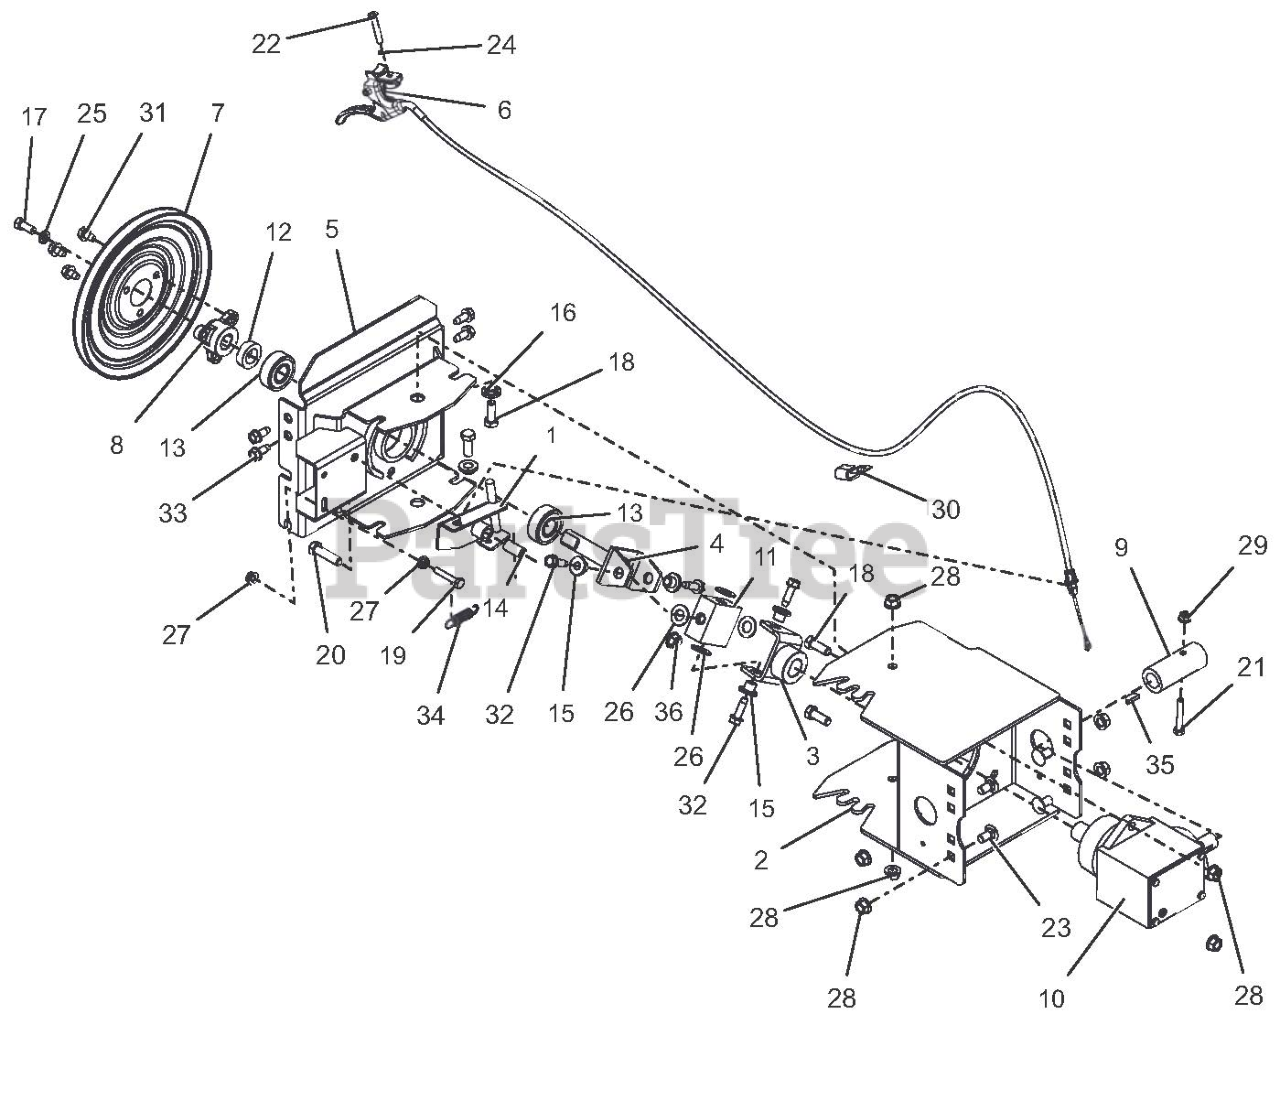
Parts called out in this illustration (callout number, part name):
1	ARM, PIVOT LOCK
2	ADAPTER, BROOM FRAME
3	JOINT,UNIVERSAL
4	JOINT,UNIVERSAL
5	ADAPTER, FRAME-20000 SERIES
6	CABLE, REMOTE BRUSH LOCK
7	PULLEY,SPIN FORM SINGLE GROOVE
8	PULLEY HUB, BOLT-ON D-BORE .75
9	HUB, COUPLING
10	GEAR BOX ASSEMBLY
11	BLOCK, UNIVERSAL
12	SPACER .755X1.250X.370
13	BRG-BALL .750X1.781X.61
14	BSHG-SLV .385X.500X1.045
15	BSHG-FLG .325X.500X.513X.875
16	BSHG-FLG .406X.88X.270X.140
17	BLT-HEX .31-24X.75 YWZC GR5
18	@BLT-HEX .38-16X1.00 GR5 YWZC
19	@BLT-HEX .25-20X1.50 GR5 YWZC
20	@BLT-HEX .38-16X1.50 GR5 YWZC
21	@BLT-HEX .25-20X1.75 GR5 YWZC
22	SCR-MCH .25-20X1.50 OVAL HD
23	@BLT-RDHDSQNK .38-16X.75 G5YZ
24	WSHR-LK-INT .250 TH TYA
25	WSHR-LK .312X.097 HVY YWZC
26	WSHR-HDND-STL-THR.515X.97X.062
27	@NUT-SPNLK-FLG .25-20 YWZC
28	@NUT-LK-TOP-FLG .38-16 YWZC
29	@NUT-LK-TOP-FLG .25-20 YWZC
30	J-CLAMP
31	@SCR-TAP .31-18X.50 HWH TR YWZ
32	@SCR-TAP .31-18X1.00 HWH TR YZ
33	@SCR-TAP .31-18X.75 HWH TR YWZ
34	SG-TENS .06X.46X2.00
35	KEY-WDRF .188X.75X.313 SAE 9
36	NUT-LK-CTR-FLG .375-16 GF ZCC
